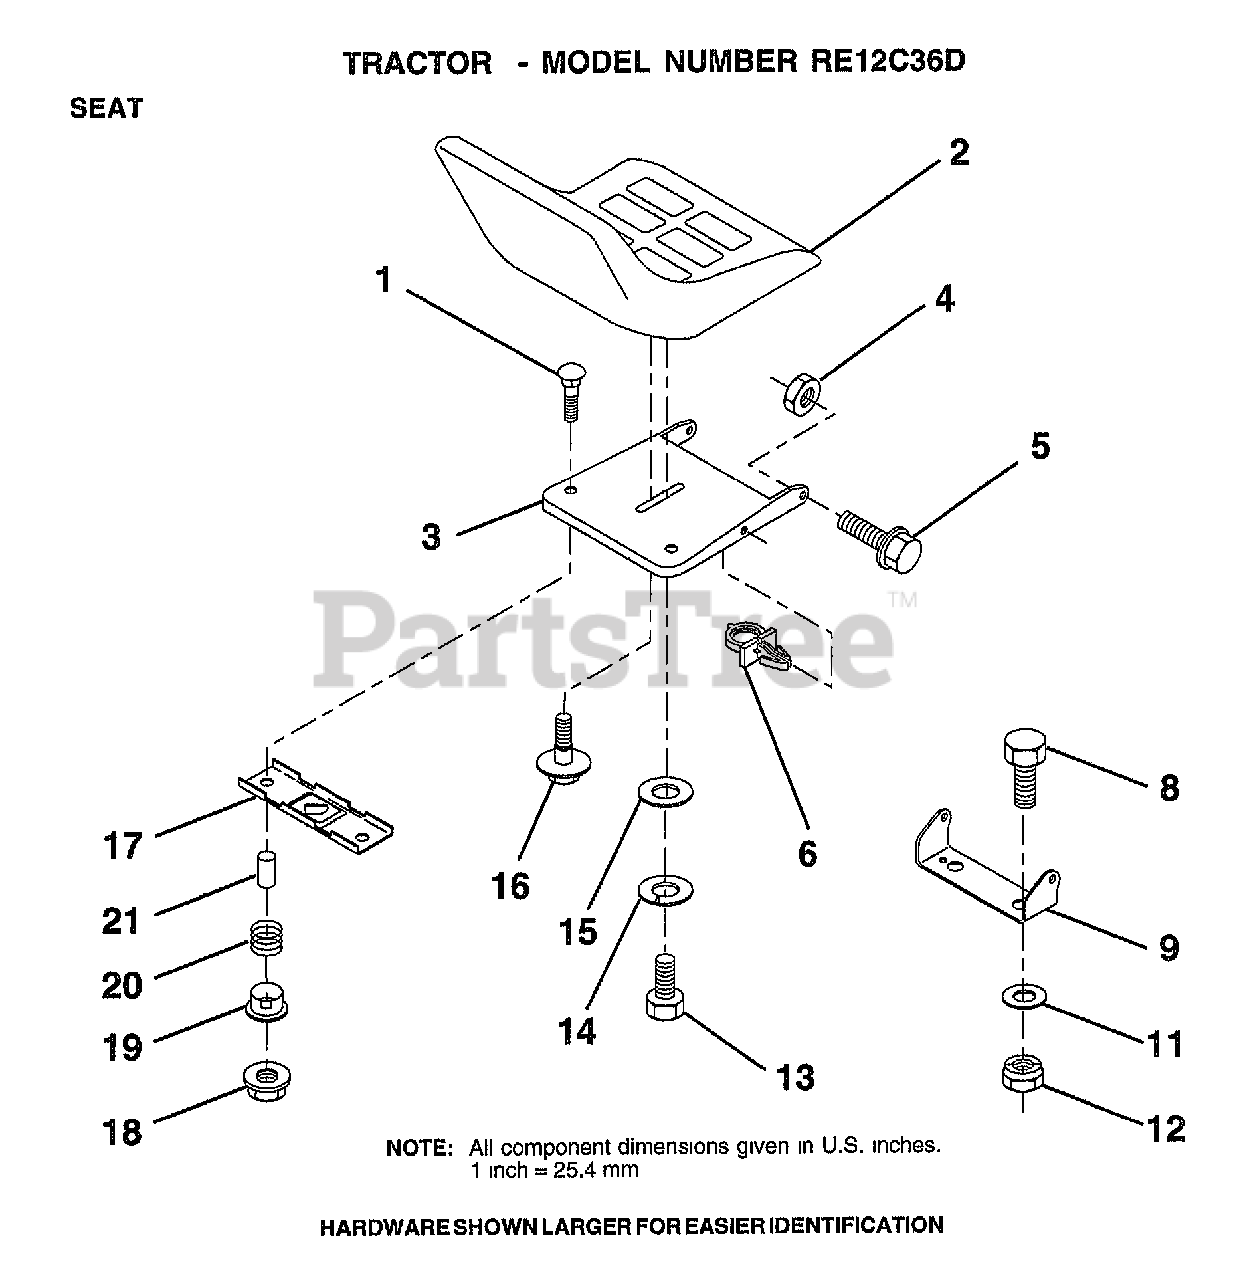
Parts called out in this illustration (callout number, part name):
1	BOLT-RD HD SQ NK
3	PAN-SEAT
4	NUT
5	BOLT
6	CLIP.PUSH-IN.HING
8	BOLT
9	BRACKET PVT SEAT
11	WASHER
12	NUT
13	BOLT
14	LOCKWASHER
15	WASHER
16	"BOLT,SHOULDER"
17	BRKT SWITCH
19	BUSHING
20	SPRING
21	SPLIT SPACER
